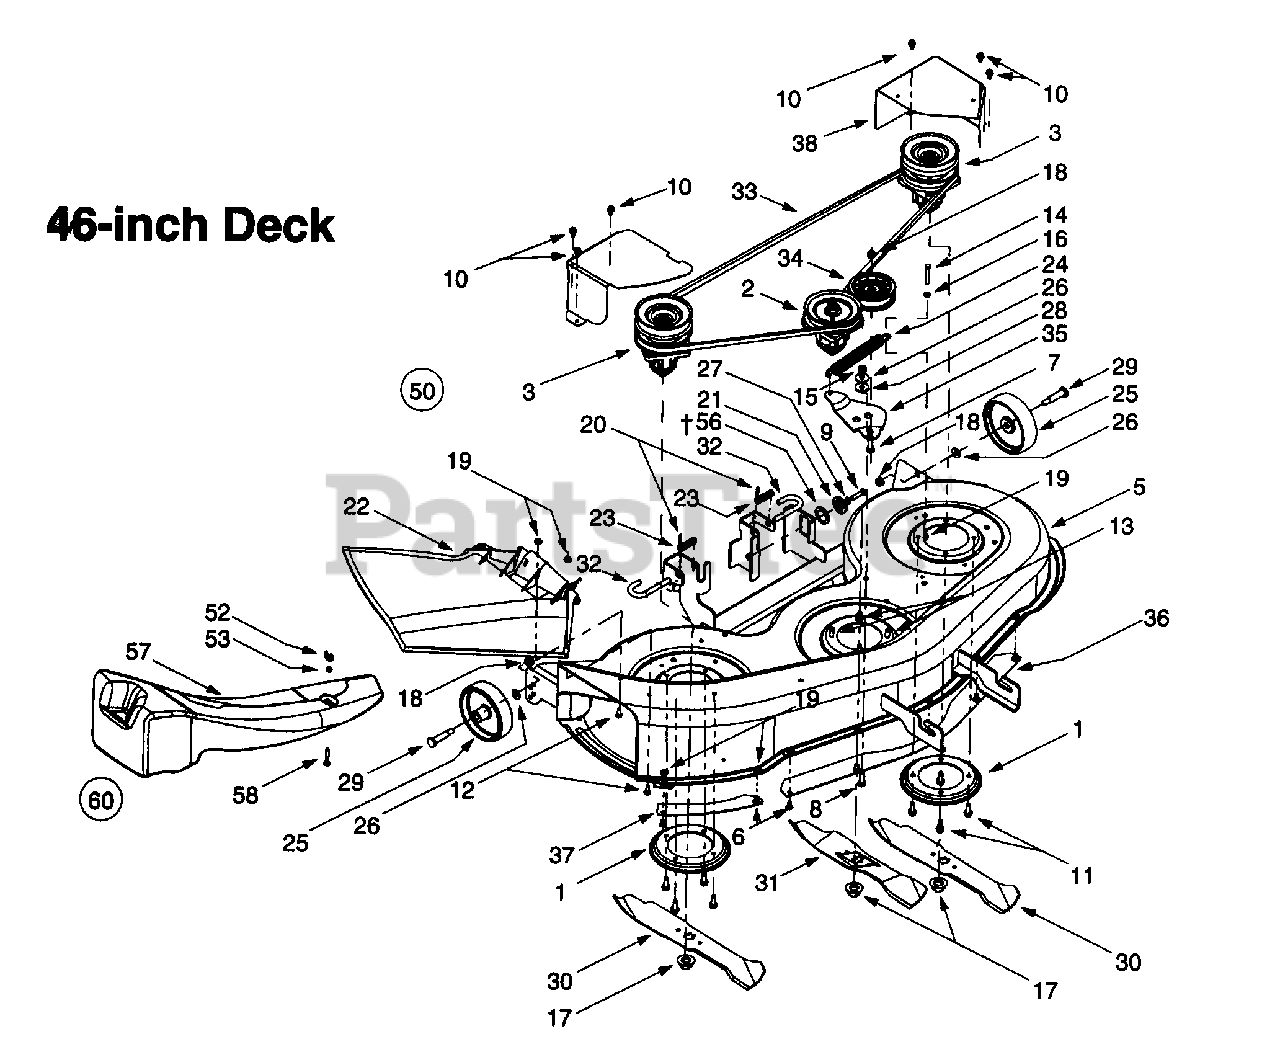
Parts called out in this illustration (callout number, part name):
3	Double Pulley Spindle Assembly
6	Carriage Screw, 1/4-20 x .5
7	Hex Cap Screw, 3/8-16 x 1.75
8	Hex Cap Screw, 3/8-16 x 1.0
9	Hex Cap Screw, 5/16-18 x 1.25
10	Self Tapping Screw,1/4-20 x .5
11	Self Tapping Screw, 5/16-18 x .875
12	Hex Cap Screw, 1/4-20 x .62
13	Self Tapping Screw, 5/16-18 x .75
14	Hex Cap Screw, 1/4-20 x 1.62
15	Hex Nut, 3/8-24
16	Center Lock Nut, 1/4-20
17	Hex Flange Nut, 5/8-18
18	Flange Lock Nut, 3/8-16
19	Hex Flange Lock Nut, 1/4-20
20	Internal Cotter Pin, .072 x 1.12
21	Deck Adjustment Gear
22	Side Discharge Chute Assembly
23	Compression Spring, .406 x .531 x 1.75
24	Extension Spring, .91 x 7.33
25	Deck Wheel, 5 x 1.38
26	Bell Washer, .401 x .87 x .063
27	Lock Washer, 5/16
28	Shoulder Spacer, .625 x .169
29	Shoulder Spacer, .498 x 1.53
30	Three-in-one Blade, Star Center, 16.28 46
31	Three-in-one Blade, Star Center, 14.88 46
32	Deck Release Pin
33	Deck Belt
34	Flat Idler Pulley, 3.5 OD
53	Center Lock Nut, 1/4-20
56	Flat Washer, 1.03 x 1.62 x .030
57	Mulch Plug, 46-inch Decks
58	Hex Cap Screw, 1/4-20 x 1.5
60	Mulch Kit, 46-inch Decks
